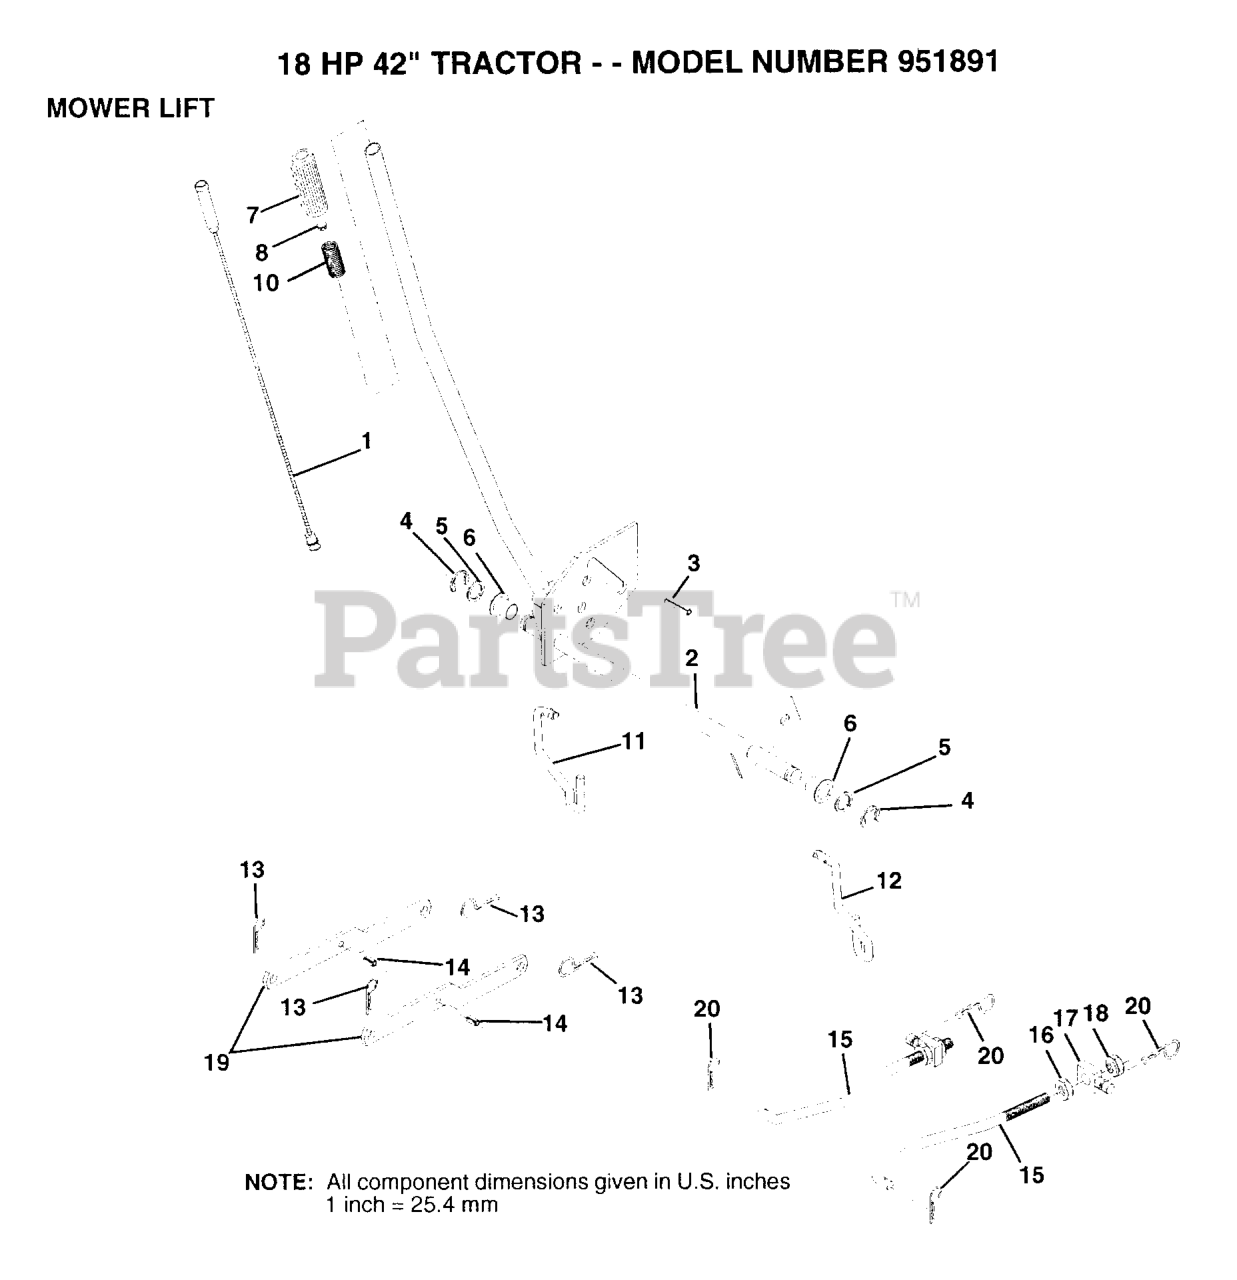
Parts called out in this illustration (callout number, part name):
1	WIRE ASM
2	SHAFT.ASM.LIFT LH
3	PIN-GROOVE LT
5	WASHER
6	NYLON BEARING
7	GRIP
11	LINK LIFT LH
12	LIFT LINK RH
14	"PIN,SPRING"
15	LINK.FRONT
16	NUT
17	TRUNION
18	NUT.LK.W/WSH.1/2.
20	RETAINER.SPRING
